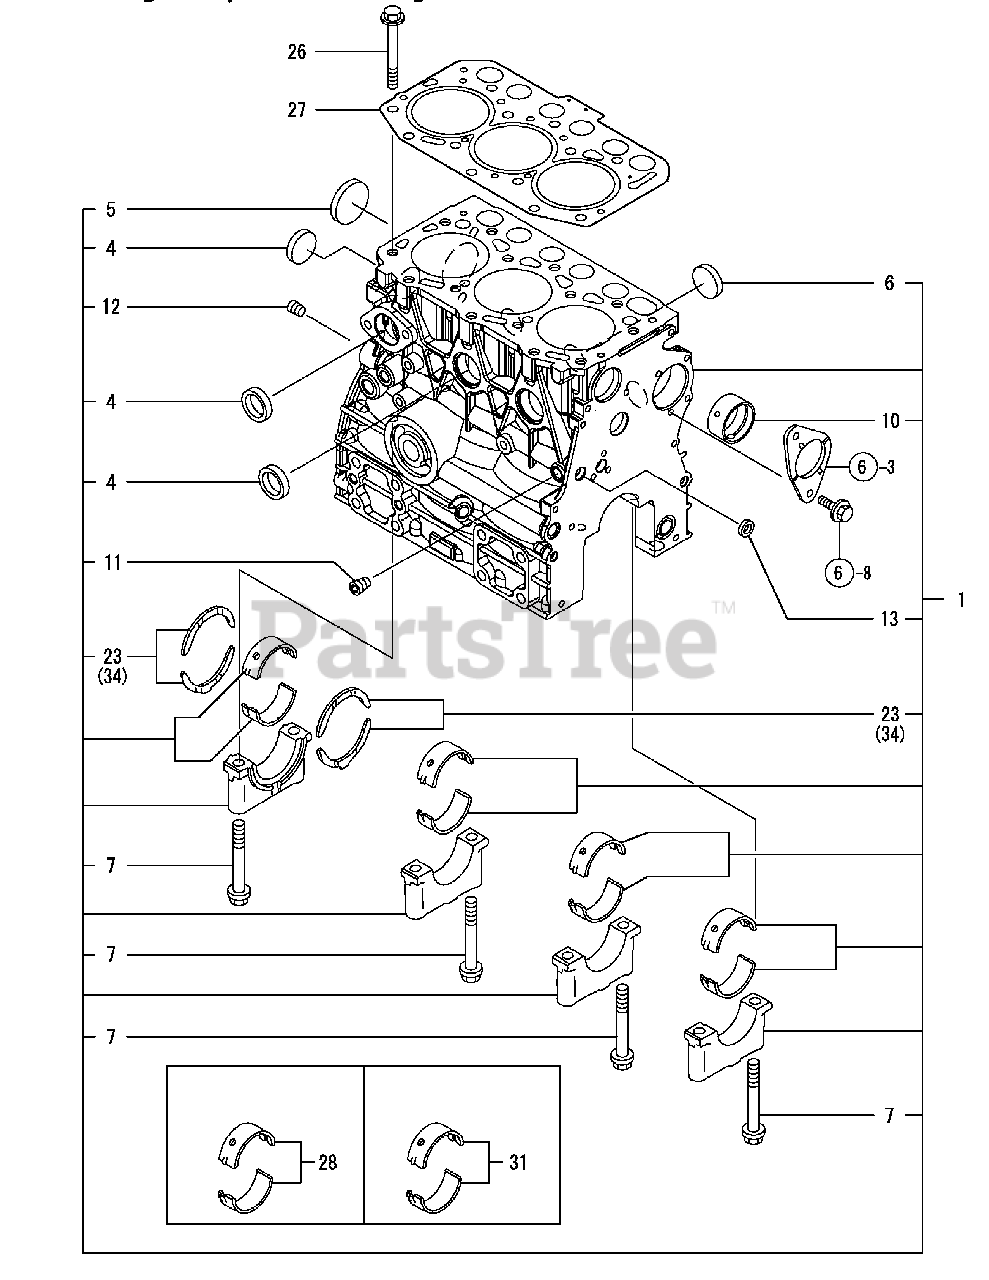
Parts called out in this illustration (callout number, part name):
1	Block Assembly, Cylinder
10	Bush, Camshaft
23	Bearing, Thrust
26	Bolt, Cylinder Head
27	Gasket, Cylinder Head
28	Main Bearing Set
34	Bearing, Thrust
